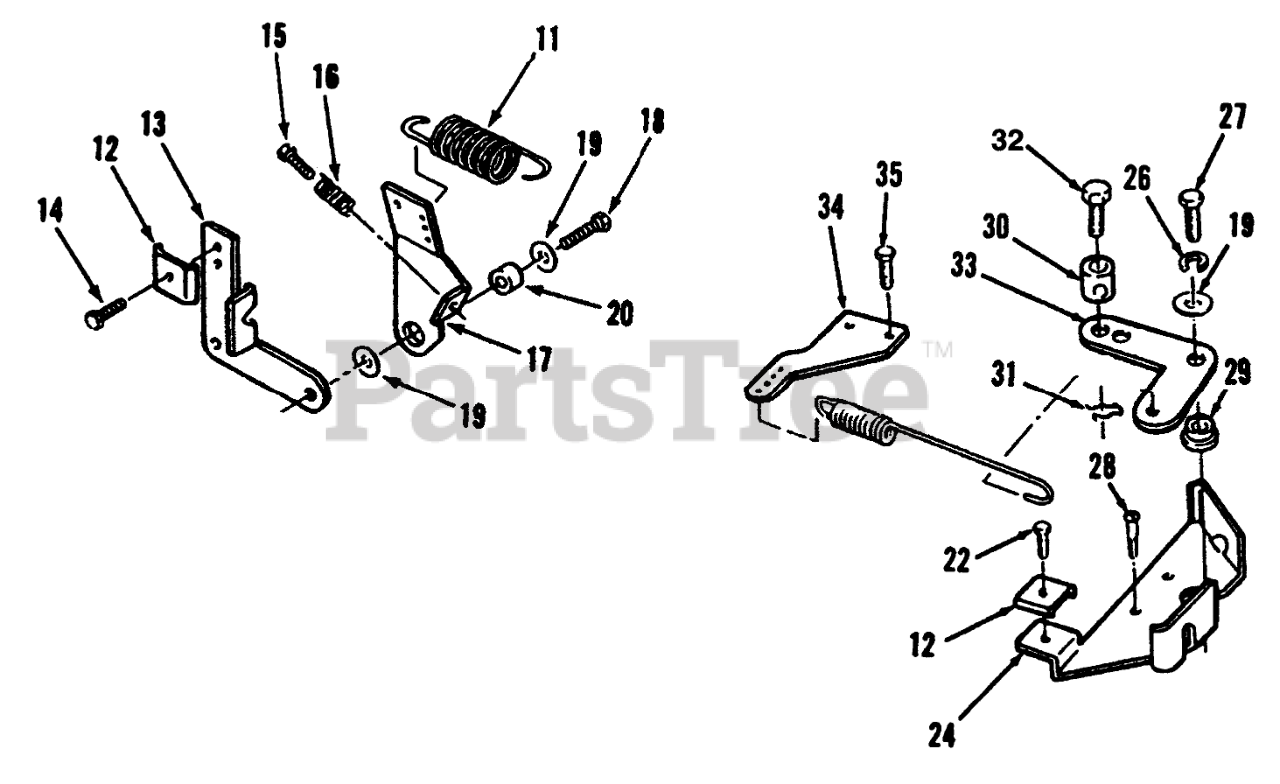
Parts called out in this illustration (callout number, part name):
11	SPRING
13	BRACKET
14	SCREW-TAPPING
15	SCREW-TAP
16	SPRING
17	GOVERNOR CONTROL ARM
18	SCREW-HWH
19	WASHER-FLAT
20	BUSHING
22	TAPPING HEX HD CS
24	BRKT-GOVERNOR CONTRL
26	WASHER-LOCK, SPRING
27	SCREW - CAP HEX HEAD
28	HEX HD CAP SCREW
29	BUSHING-GOV CONTROL
31	PIN-COTTER
32	SCREW
33	Governor Control Arm
34	ADAPTER-GOV ARM
35	Screw
